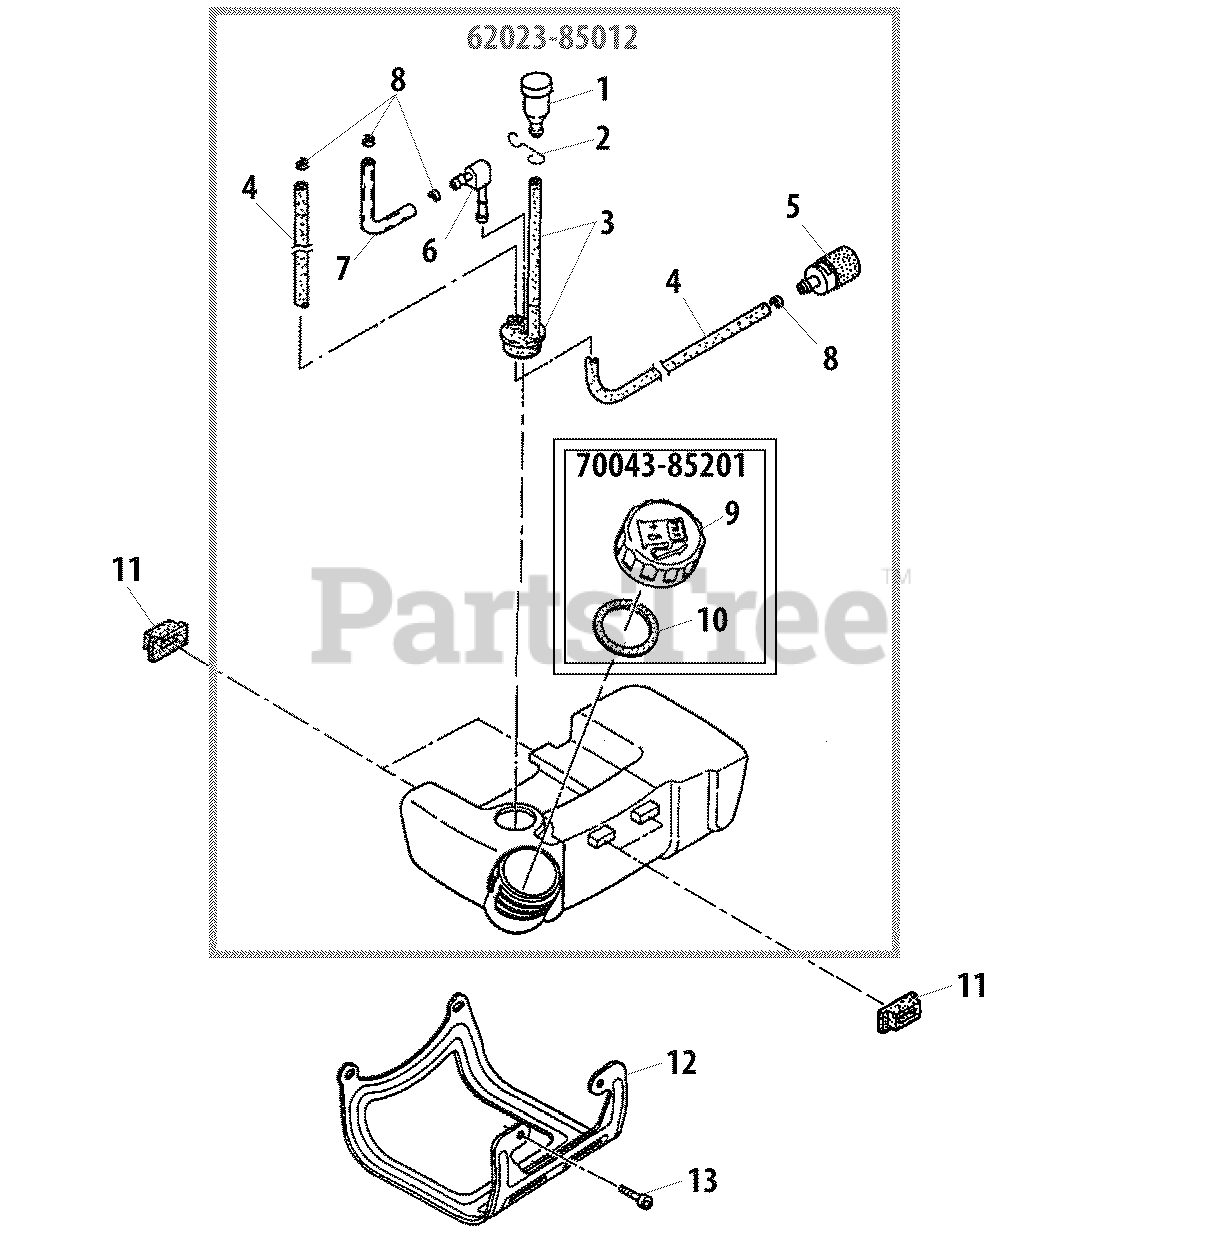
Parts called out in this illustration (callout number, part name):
1	VENT ASSY
2	CLIP, VENT ASSY
3	GROMMET, FUEL W/VENT PIPE
4	PIPE, FUEL
5	FILTER, FUEL 125-528
6	CONNECTOR, PIPE
7	PIPE, FUEL RETURN
8	CLIP Ø6
9	CAP, FUEL
10	GASKET, FUEL CAP
11	CUSHION, FUEL TANK
12	GUARD, METAL FUEL TANK
13	BOLT M5×12
62023-85012	FUEL TANK ASSY
70043-85201	CAP ASSY, FUEL
